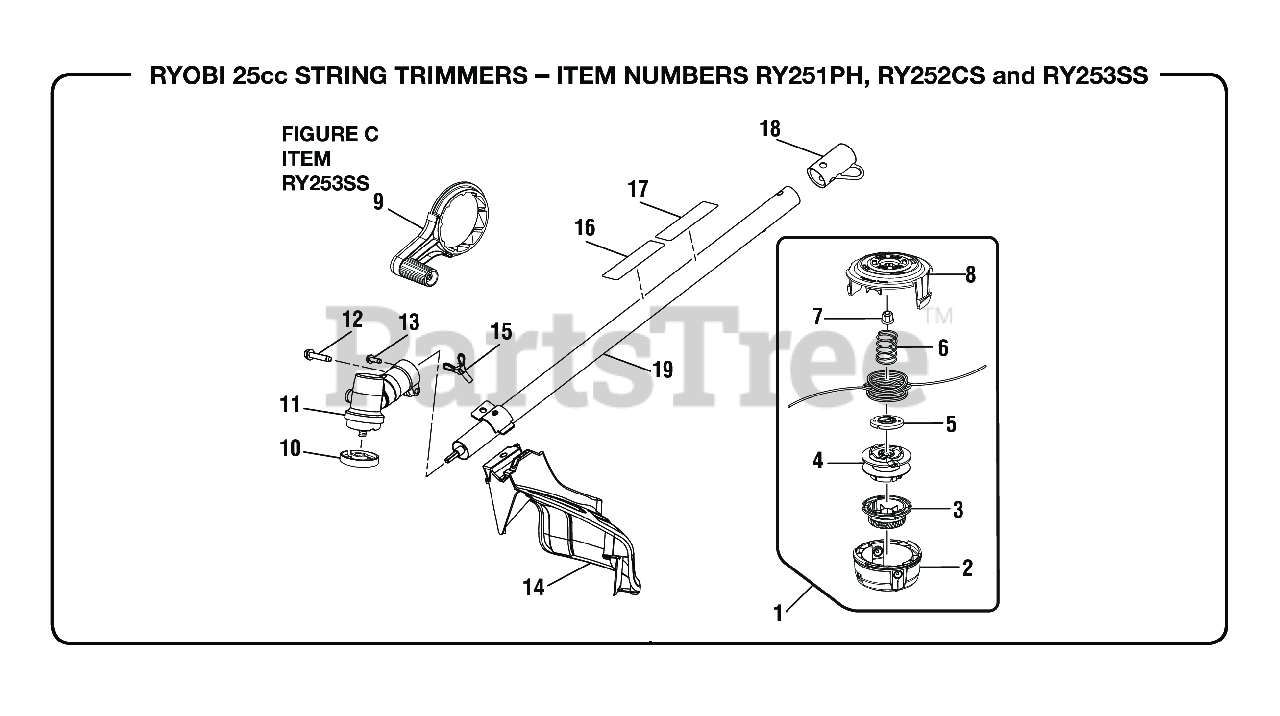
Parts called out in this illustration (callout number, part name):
1	Trimmer Head Assembly (.095)
2	Lower Housing
3	Bump Knob (Green)
4	Spool Assembly
5	String Guide
6	Compression Spring
7	Hex Nut (M8, Left Hand Threads)
8	Upper Housing
9	Crank Handle Assembly
10	FLANGED WASHER
11	Gear Case Assembly
12	Screw (1/4-20 x 1-1/4 in., Hex Washer Hd. S.T.)
13	Screw w/Washer (10-24 x 5/8 in., Hex Hd. T.F.)
14	Grass Deflector Assembly (Inc. Key No. 16)
15	Screw (#1/4-20 x 1-1/4 in. Hex Washer Hd.)
16	Ryobi EXPAND-IT Label
17	Warning Icon Label
18	Storage Hanger Cap
19	Straight Shaft Assembly
